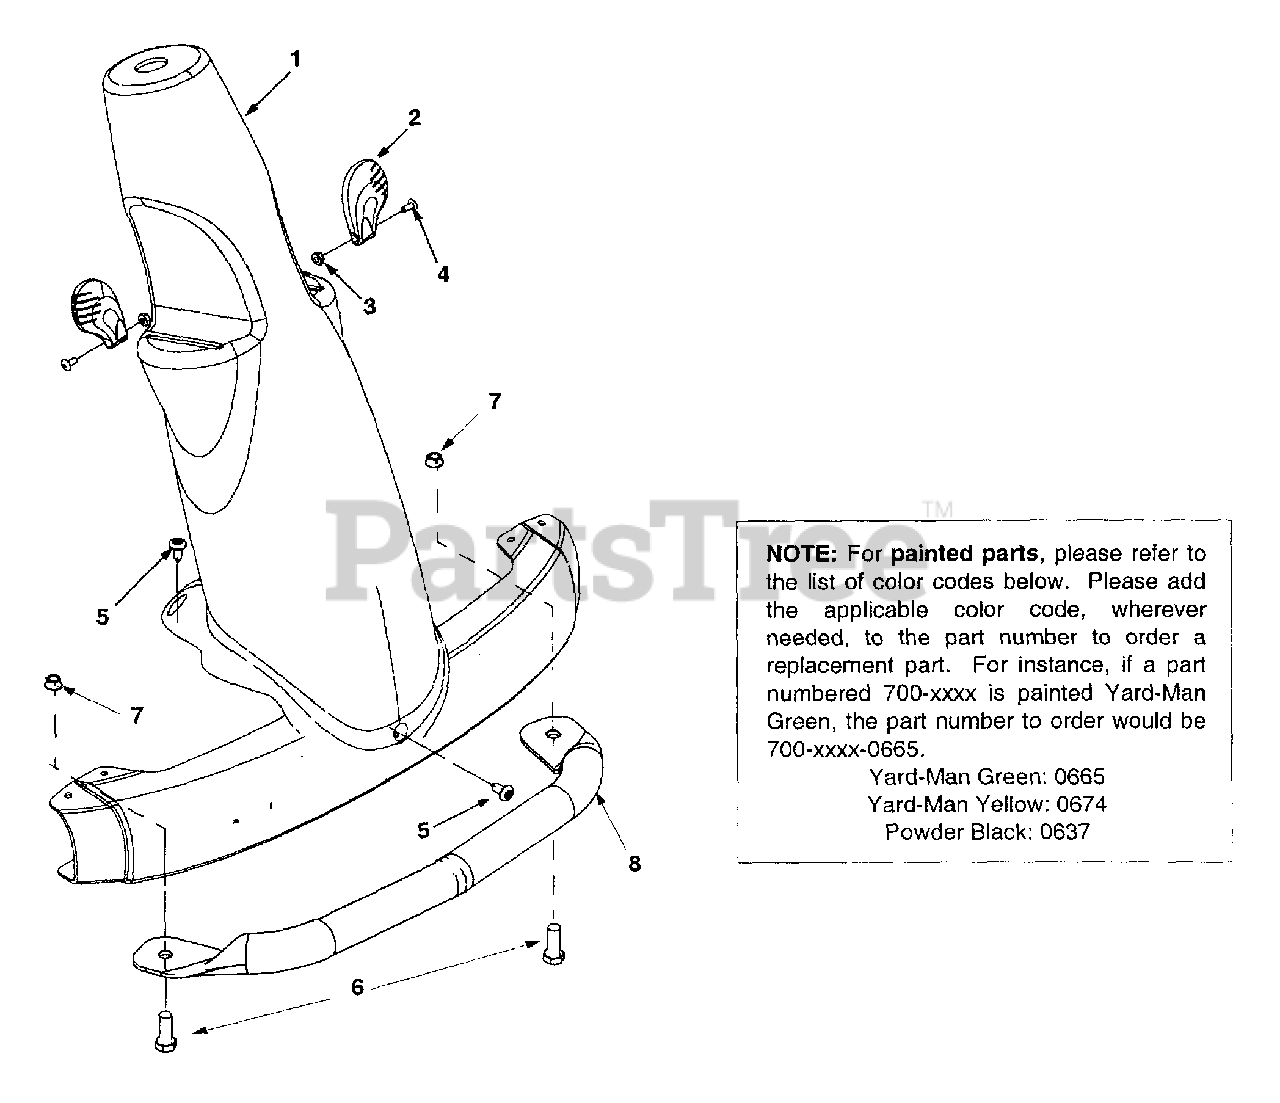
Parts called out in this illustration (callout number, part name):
1	Steering Column: Green
2	Control Knob
3	Hex Nut 8-32
4	Pan Head Machine Screw #8-32
5	Hex Screw TT 1/4-20 x .50"
6	Hex Screw 3/8-16 x 1.0"
7	Lock Nut
